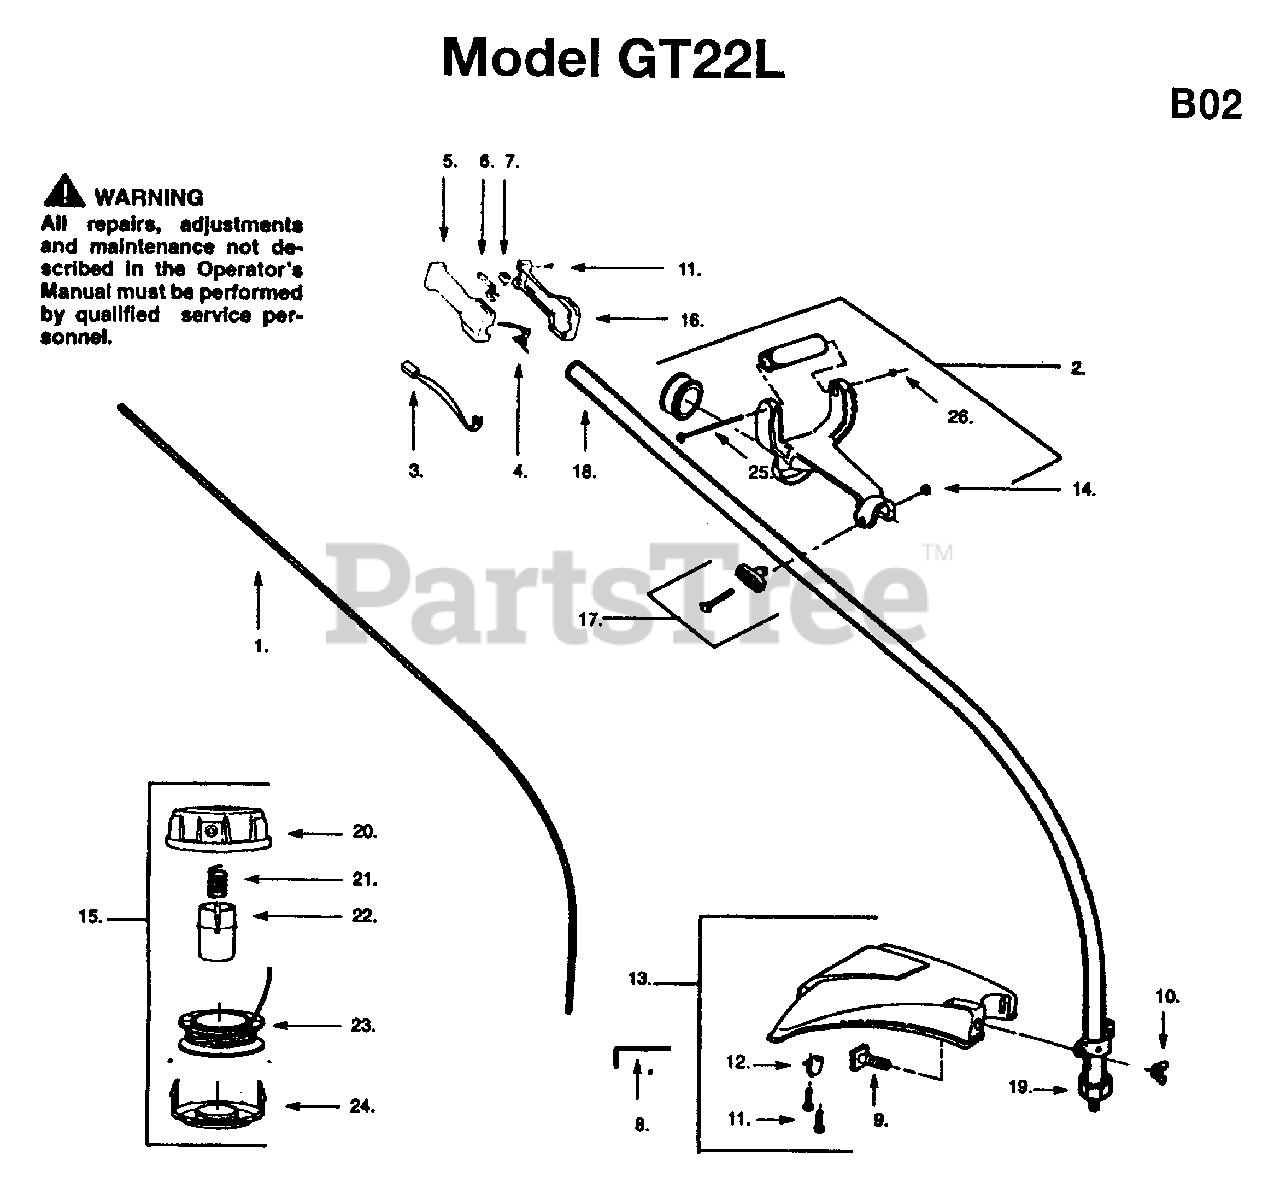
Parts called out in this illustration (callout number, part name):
1	REPL BY 530 09 45-51
2	ASS'Y-HANDLE ANTIVIB
4	THROTTLE TRIGGER
7	REPL BY 530 06 95-72
8	ALLEN KEY
9	BOLT, TYPE 2
10	NUT - HANDLE/SHIELD
11	SCREW-10-14 X 13/16 (PL
12	REPL BY 530 09 52-49
15	CUTTING HEAD ASSEMBLY
17	KIT "T" HANDLE
18	DRIVE SHAFT
20	HUB AND SHAFT ASSY
23	SPOOL W/ LINE NLA
25	SCREW-12-24 X 4-11/16 P
26	NUT-12-24 (HEX)
